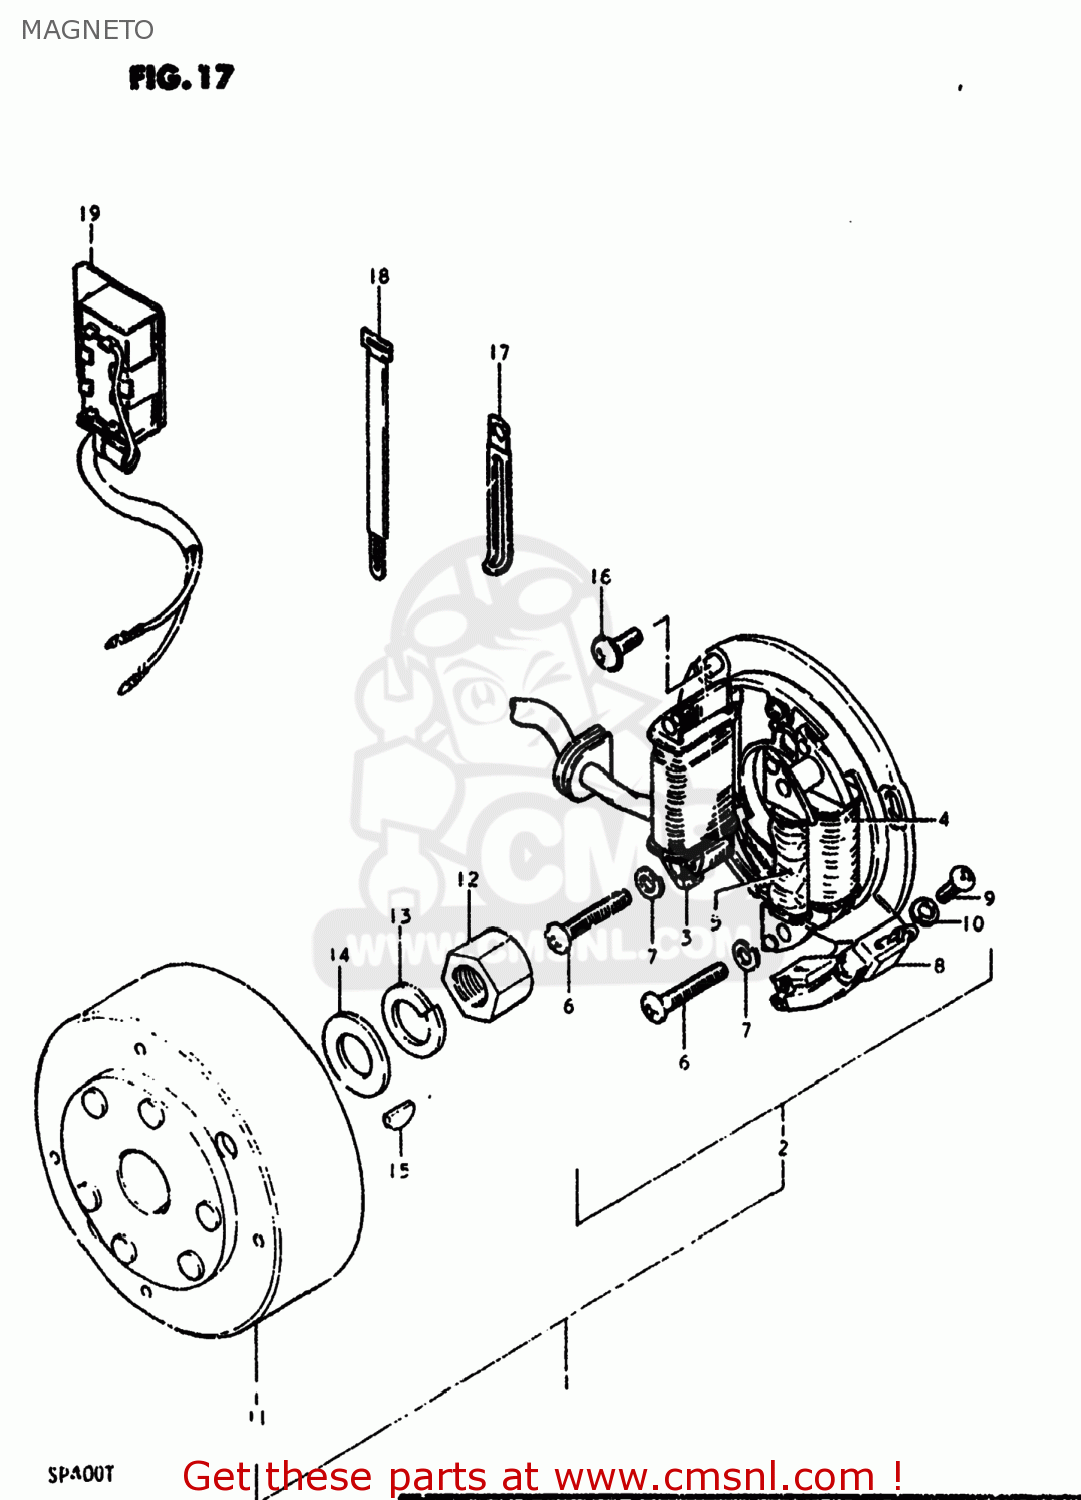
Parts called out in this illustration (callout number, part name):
1	MAGNETO ASSEMBLY
2	STARTER ASSY
3	COIL,LIGHTING
4	COIL,PRIMARY
5	COIL,PULSER
6	SCREW
7	LOCK WASHER
8	COIL,PULSER
9	SCREW
10	LOCK WASHER
11	ROTOR,FLYWHEEL
12	NUT
13	LOCK WASHER
14	WASHER(14X27X3)
15	KEY 4MM
16	SCREW(5X14)
17	CLAMP
18	CLAMP
19	REGISTER ASSEMBLY
